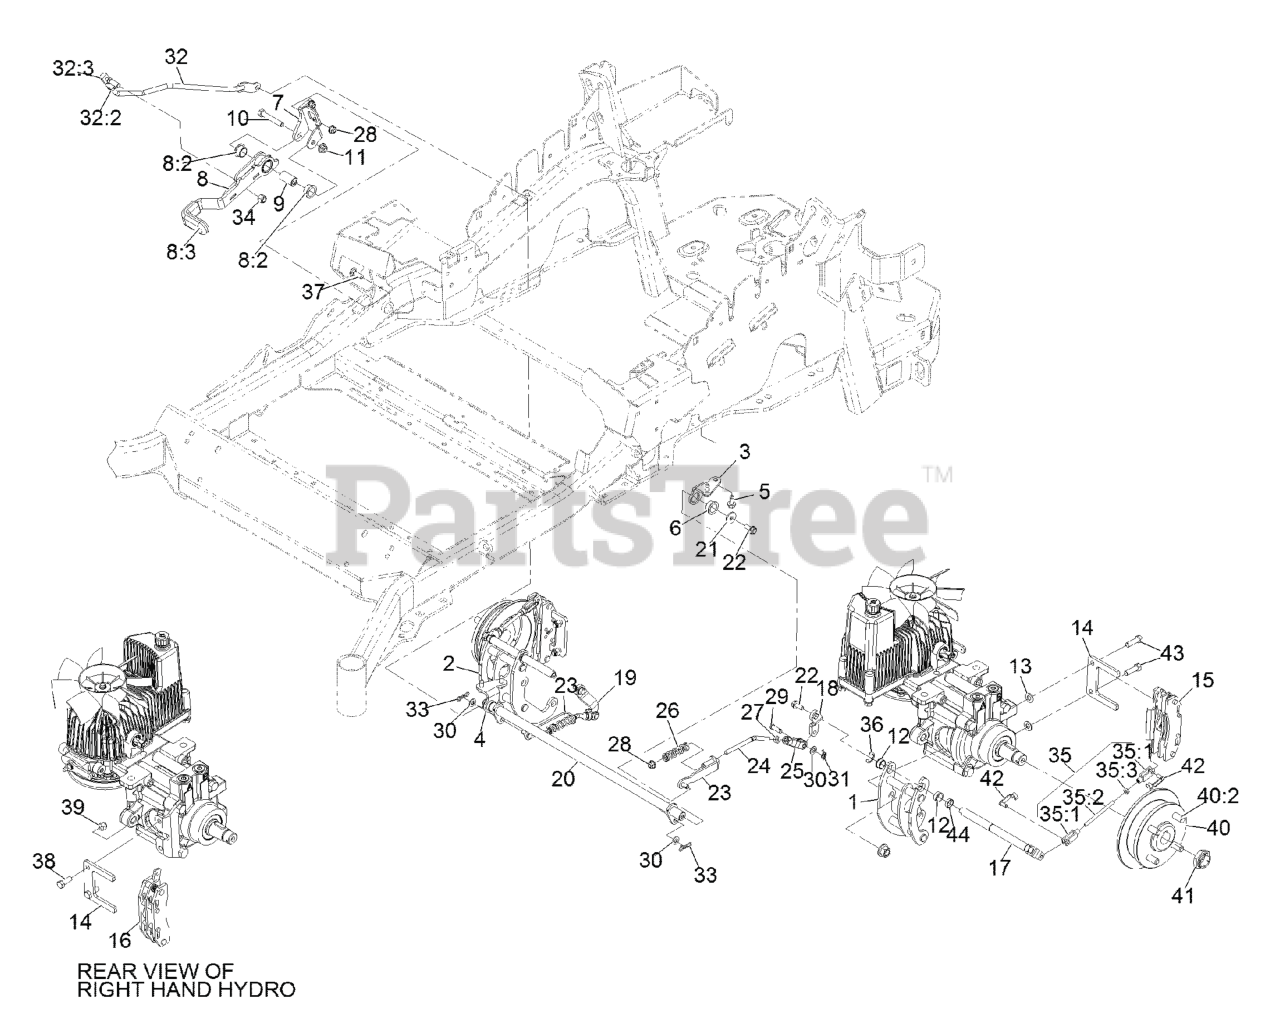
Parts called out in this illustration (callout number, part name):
1	MOUNT-BELLCRANK, LH
2	MOUNT-BELLCRANK, RH
3	MOUNT-PIVOT, LH
4	MOUNT-PIVOT, RH
5	Screw-HWH 5/16-18 X 3/4 Tf
6	BUSHING-FLANGE
7	BRACKET-MOUNT
8	BRAKE LEVER ASM
8:2	BUSHING-FLANGE
8:3	GRIP-LEVER
9	HANDLE-PIVOT, BRAKE
10	SCREW-HH
11	NUT-HF, NI
12	BUSHING
13	WASHER-FLAT
14	PLATE-MOUNT, BRAKE
15	CALIPER-BRAKE
16	CALIPER-BRAKE, RH
17	BELLCRANK
18	ARM-INNER, LH
19	ARM-INNER, RH
20	SHAFT-CROSS
21	WASHER-FLAT
22	SCREW-HHF
23	BRACKET-L
24	LINKAGE-MID
25	YOKE-OFFSET
26	SPRING-COMPRESSION
27	NUT-JAM
28	NUT-HF, NI
29	PIN-CLEVIS
30	WASHER-PLAIN
31	PIN-COTTER, LOCKING
32	FRONT LINKAGE ASM
32:2	END-TIE ROD, RH
32:3	NUT-HJ
33	PIN-COTTER, LOCKING
34	NUT-LOCK
35	REAR LINKAGE ASM
35:3	NUT-JAM
37	BOLT-CARR
38	SCREW-HH
39	NUT-LOCK, NI
40	WHEEL HUB ASM
40:2	STUD-WHEEL
41	LOCKNUT
42	PIN-CLEVIS, SPRING
43	SCREW-LOCK, PATCH
